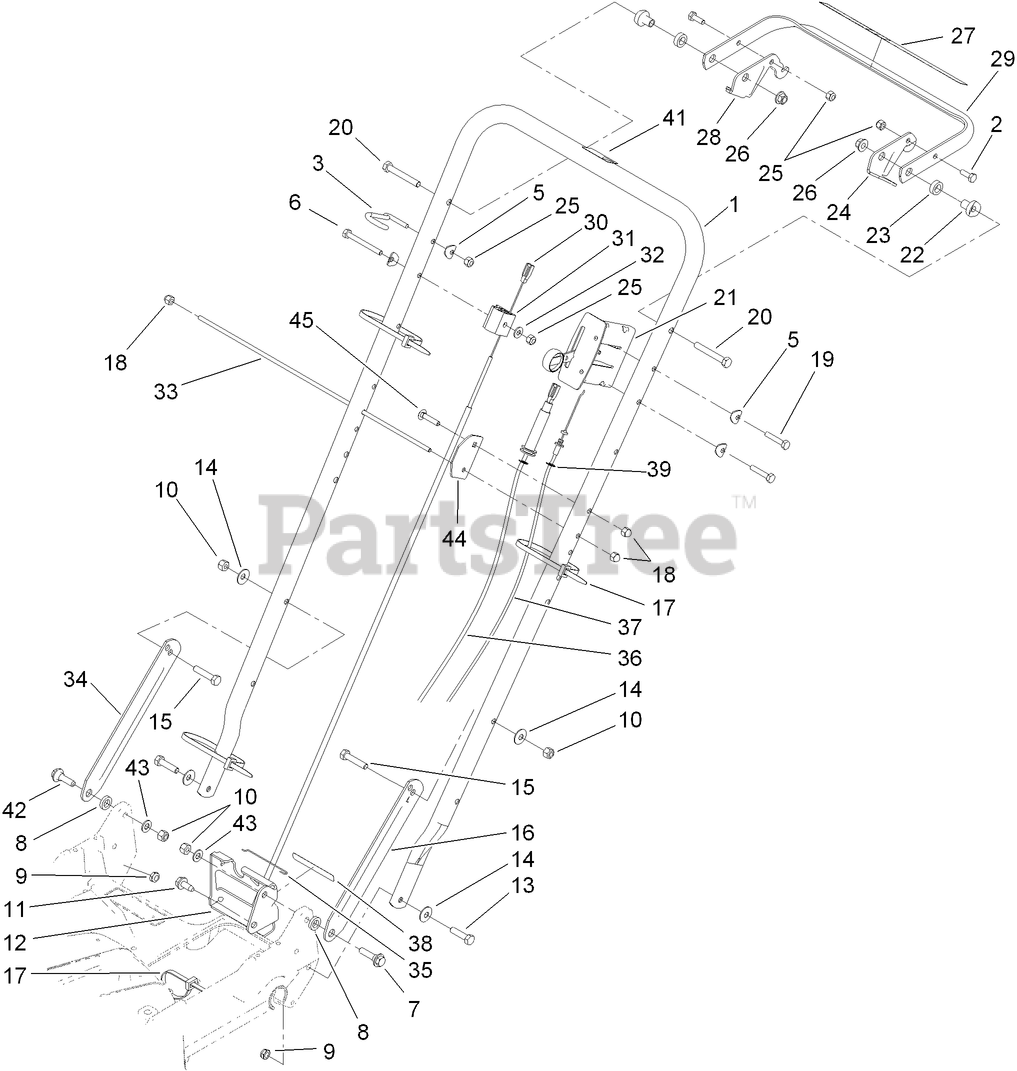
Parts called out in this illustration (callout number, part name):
2	SCREW-HH
3	GUIDE-ROPE
5	WASHER
6	SCREW-HH
7	SCREW-SHOULDER
8	SPACER
9	NUT-LOCK, NI
10	NUT-LOCK, NI
11	SCREW-HWHTF
12	BRACKET-ADJUSTMENT, TRACTION
13	SCREW-HH
14	WASHER-BELLEVILLE
15	SCREW-HH
16	LATCH-HANDLE, LH
17	TIE-CABLE
18	NUT-CAP
19	SCREW-HH
20	SCREW-HH
21	CONTROL-HEAD, THROTTLE
22	SPACER-SUPPORT
23	SPACER-NYLON
24	LEVER-CONTROL
25	NUT-LOCK, NI
26	NUT-LOCK, NI
27	DECAL-TRACTION
28	LEVER-CONTROL
29	BAR-CONTROL
30	CABLE-CONTROL, BRAKE
31	SUPPORT-CABLE
32	WASHER-FLAT
33	ROD-SUPPORT, BAG
34	LATCH-HANDLE, RH
35	RETAINER-CABLE
36	CABLE-TRACTION
37	THROTTLE CABLE ASM
38	DECAL-POSITION, GEAR
39	E-RING
41	DECAL-PROTECTION, EAR
42	SCREW-SHOULDER
43	WASHER-PLAIN
44	PLATE-ALIGNING, BAG
45	SCREW-CARR
